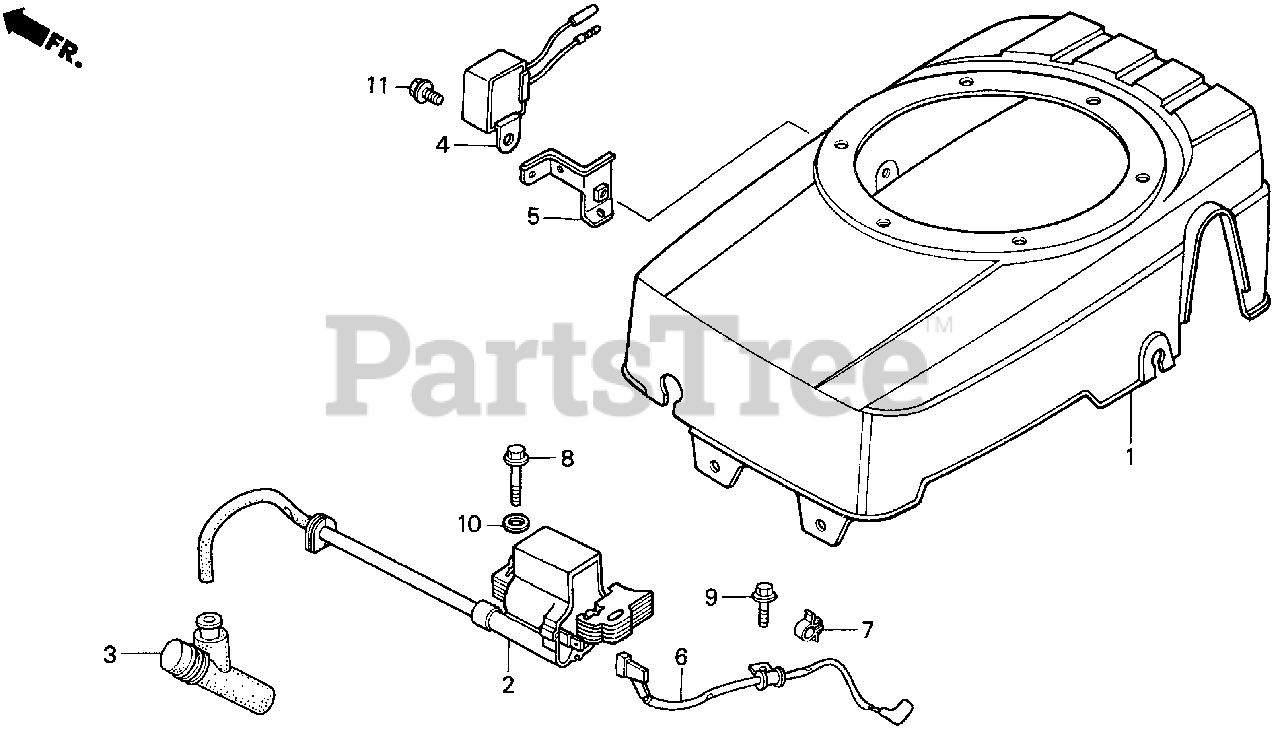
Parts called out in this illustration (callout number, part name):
1	COVER, FAN *R8* (BRIGHT RED)
2	COIL ASSY., IGNITION
3	CAP ASSY., NOISE SUPPRESSOR
6	WIRE, STOP SWITCH (BRAKE)
7	HOLDER, STOP SWITCH WIRE
7	CLIP, WIRE HARNESS (6MM) (WHITE)
8	BOLT, FLANGE (6X25)
9	BOLT, FLANGE (5X10)
